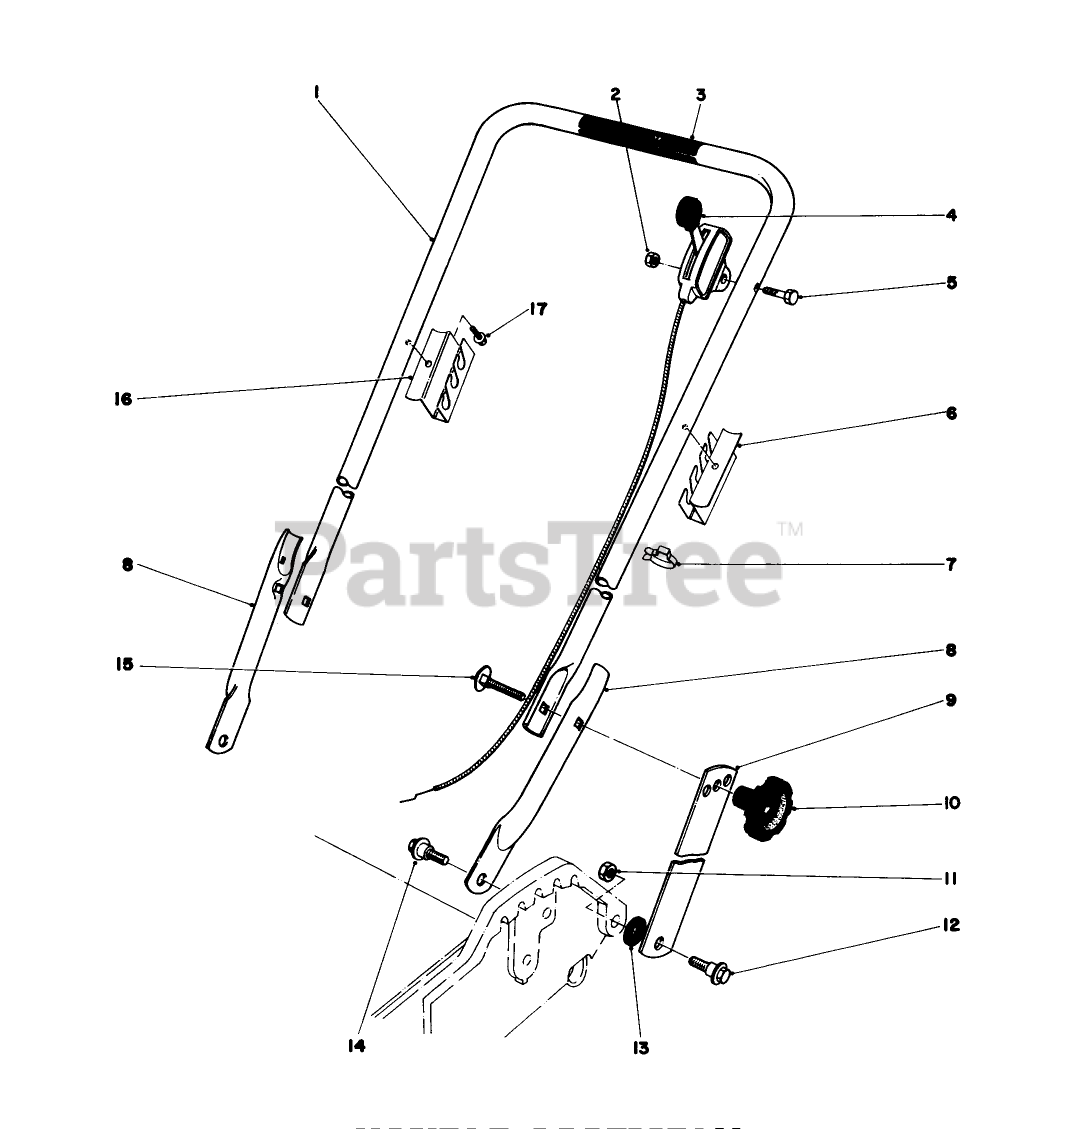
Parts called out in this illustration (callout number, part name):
5	SCREW-HH
7	BOWDEN CLIP
12	SCREW-SHOULDER
13	SPACER
14	SCREW-SHOULDER
15	SCREW-HANDLE
17	SCREW-HWHTF
